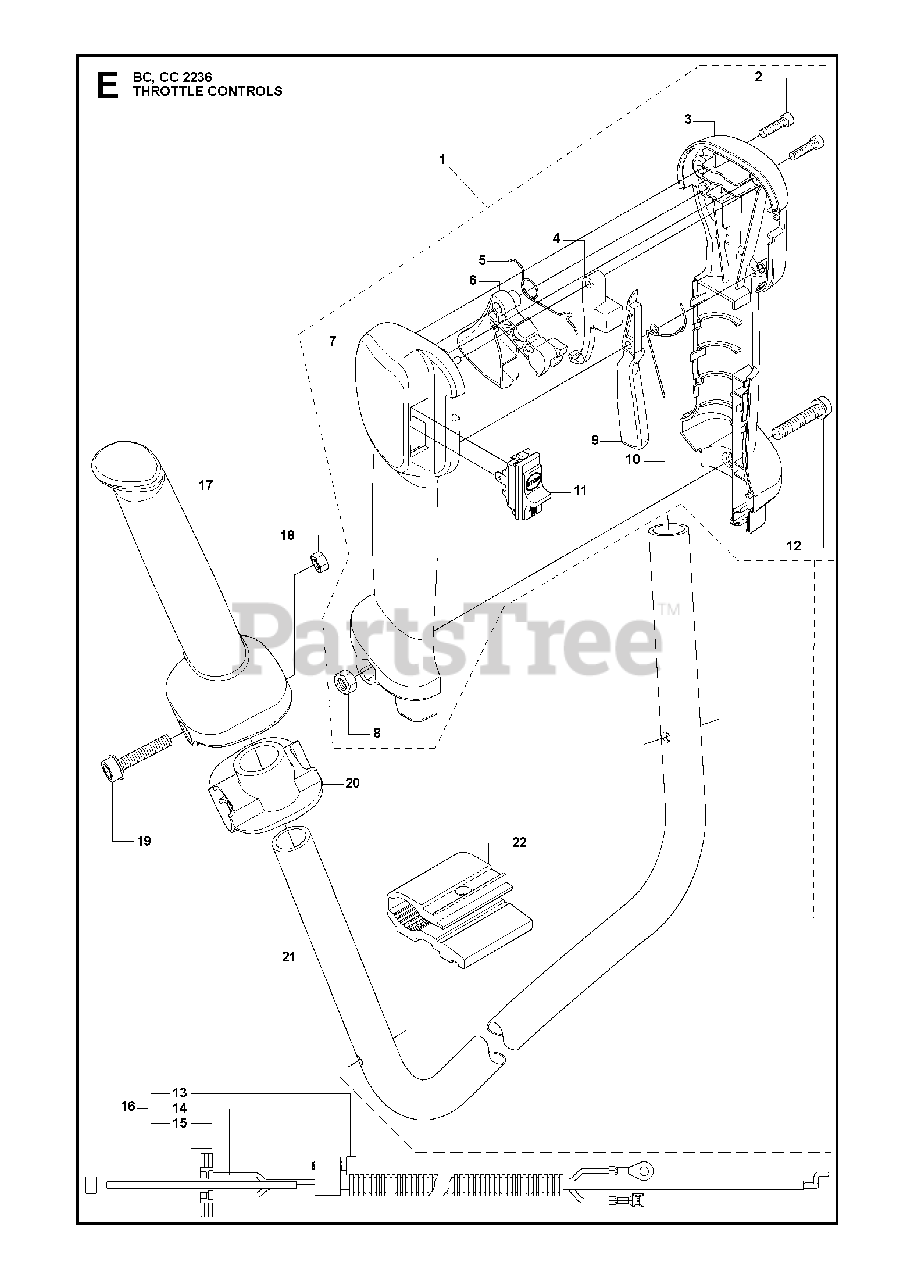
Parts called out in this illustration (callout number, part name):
2	SCREW
3	HANDLE RIGHT
4	SWITCH
5	SPRING
6	THROTTLE CONTROL
7	HANDLE LEFT
8	NUT
9	THROTTLE CONTROL
10	SPRING
11	STOP BUTTON
12	%SCREW
13	SCREW
14	SHORT CIRCUIT CABLE
15	THROTTLE WIRE
16	WIRING KIT COMPLETE
